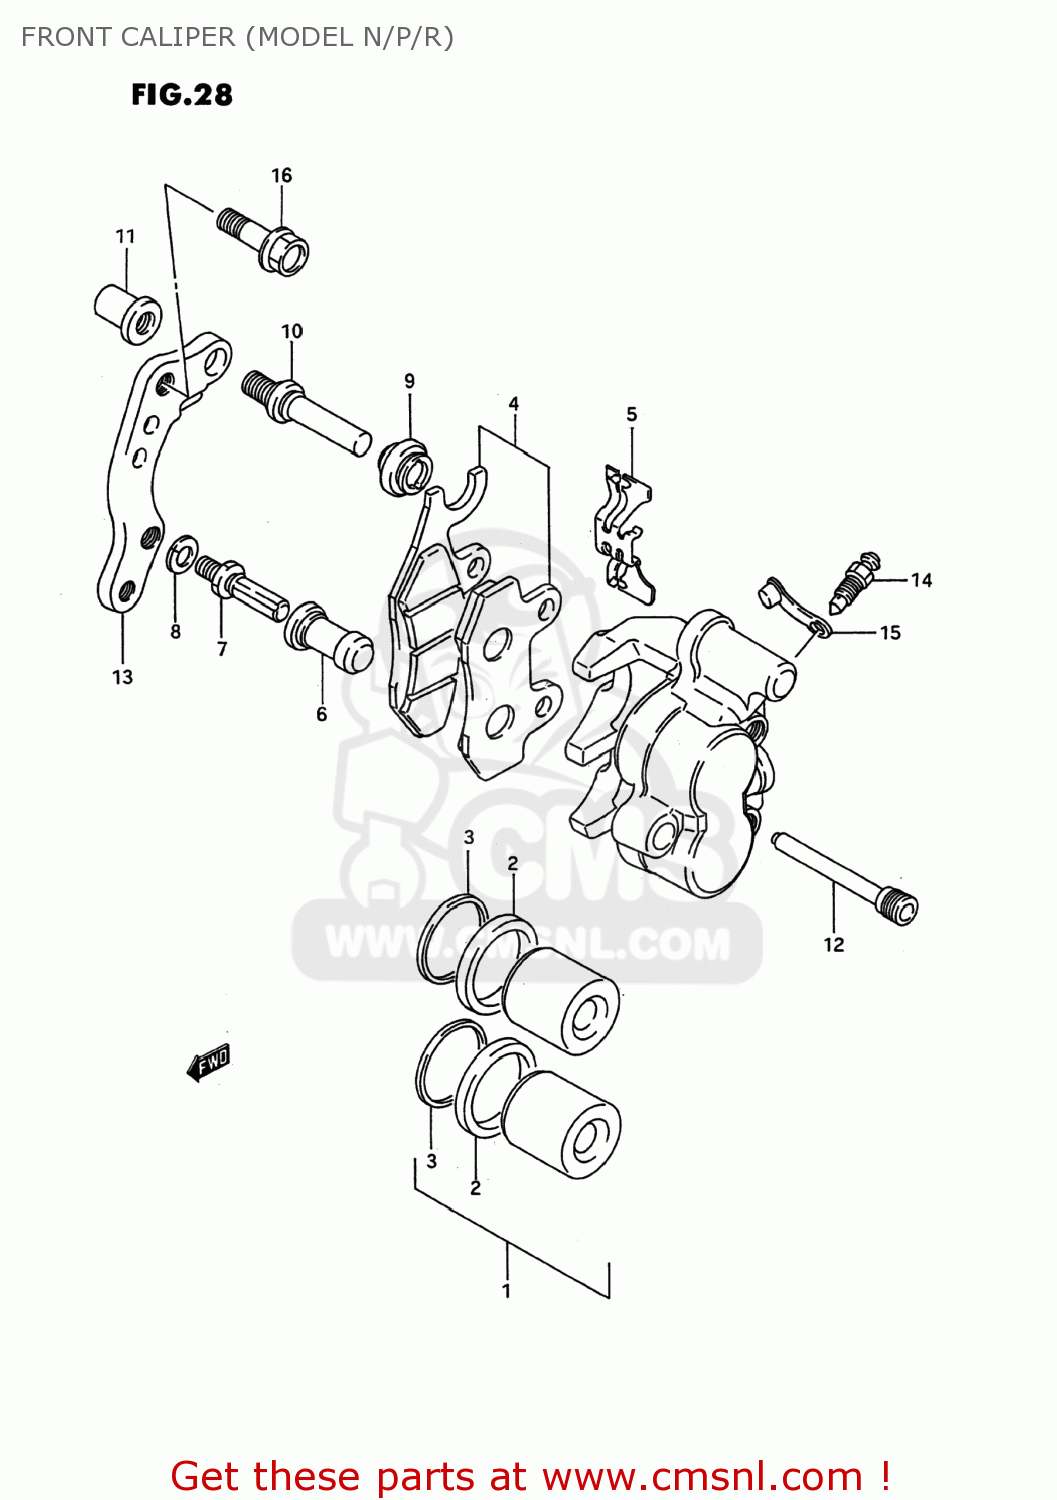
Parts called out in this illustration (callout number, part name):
1	PISTON SET
2	SEAL,PISTON
3	SEAL,DUST
4	PAD SET (NAS)
5	SPRING,PAD
6	BOOT
7	BOLT
8	WASHER
9	BOOT
10	PIN,SLIDE
11	NUT
12	PIN,HOLDER
13	BRACKET
14	BLEEDER
15	CAP,BLEEDER
16	BOLT(8X35)
